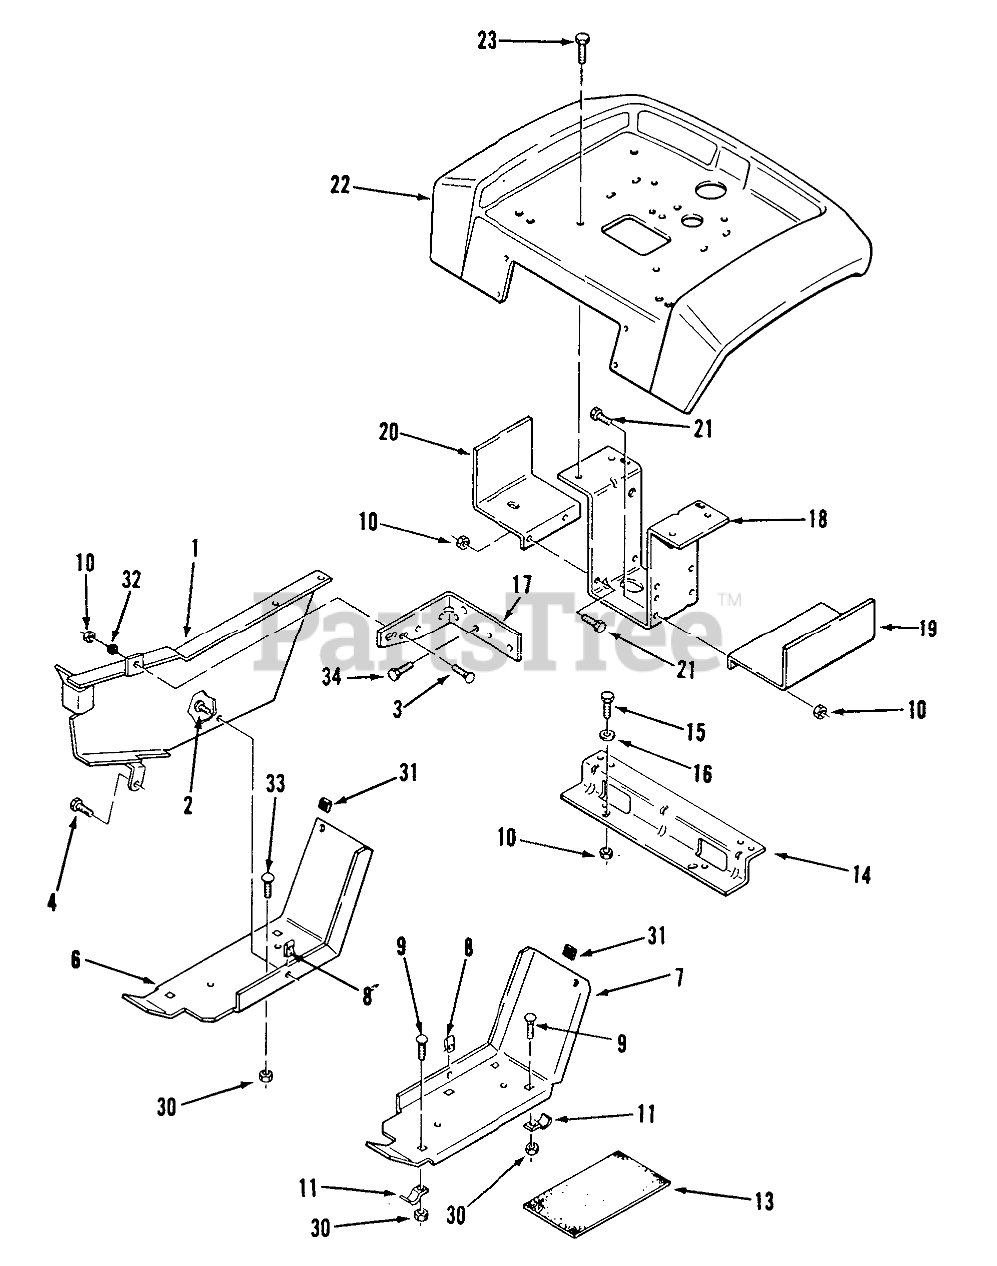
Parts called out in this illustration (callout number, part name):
1	Belt Guard
2	Screw
3	Bolt
4	SCREW
6	Footrest-RH
7	FOOTREST LH R
9	Bolt
10	Nut
11	BRACKET
13	PAD FOOTREST
14	BRACKET-FENDER B
15	Bolt
16	WASHER 5/16 SAE
17	BRACKET-BELTB
18	Bracket-Fender Support
19	Fuel Tank Support LH
20	Support-FueITank RH
21	Bolt
22	Fender
23	SCREW
24	WASHER 5/16 SAE
30	Nut
31	BUMPER
32	NUT-PUSH
33	Bolt-Carriage
34	Bolt
